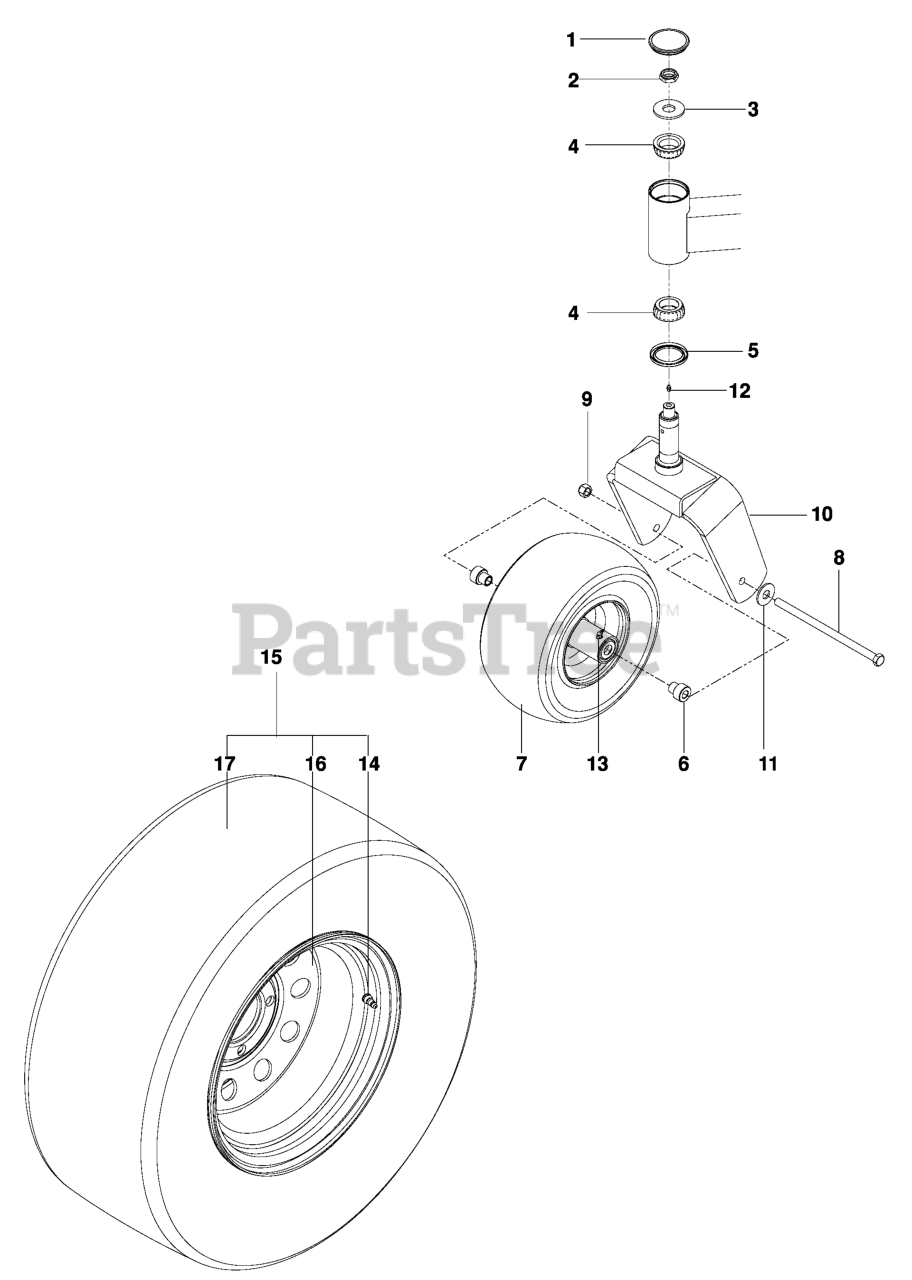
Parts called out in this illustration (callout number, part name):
2	NUT, 3/4-16 HEX THIN NYLOC ZD
3	WASHER, 3/4 HARDENED
4	BEARING W/CUP TAPPER ROLLER
5	SEAL, BEARING
6	AXLE SPACER
7	TIRE, 13 X 6.5-6 NO FLAT
8	HEX SCREW 1/2-13 X 9.5 GR5
9	NUT, 1/2-13 HEX FLG NYLOC ZD
10	FORK.CASTER.ORANGE
11	WASHER 1/2" FLAT
12	ZERK
13	ZERK
14	VALVE STEM TR-412
15	WHEEL/TIRE.ASM SILV 23X10.5-12
16	RIM, 12 X 8.5, 1.125" NEG OS
17	TIRE.TURF.MASTER.23X10.5-12
